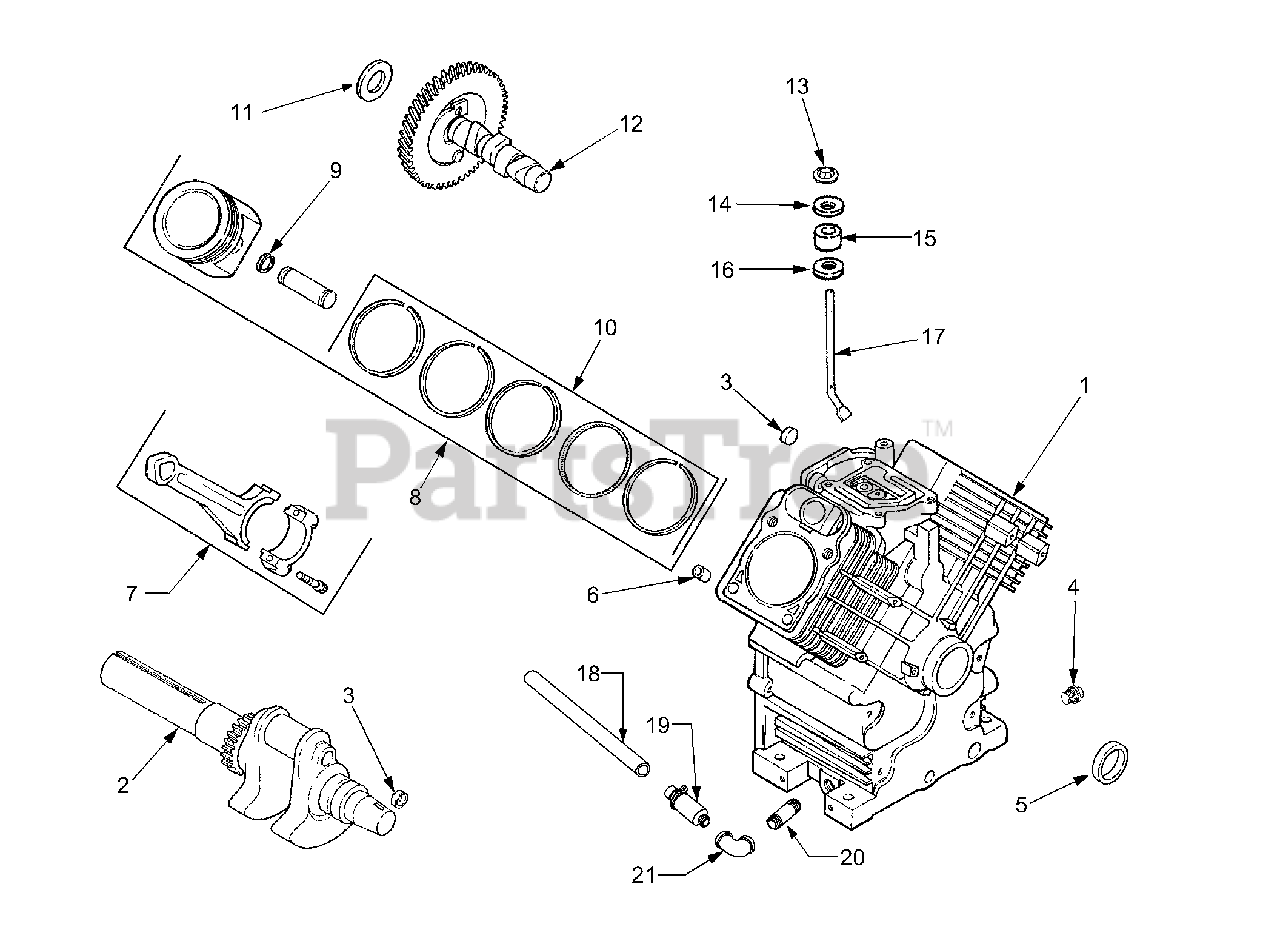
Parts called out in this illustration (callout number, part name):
1	Engine, Complete
2	Crankshaft
3	Plug, Cup
4	Plug, Hex Head, 3/8 NPTF
5	Seal, Oil
6	Pin, Dowel Locating
7	Rod, Connecting, Std
8	Piston w/Ring Set, Std
9	Retainer, Piston Pin
10	Ring Set, Std
11	Shim, Camshaft, .0320
12	Camshaft
13	Ring, Retainer
14	Washer, Nylon
15	Seal, Governor Cross Shaft
16	Washer, Plain
17	Shaft, Governor Cross
18	Hose, Oil Drain
19	Drain, Oil
20	Pipe, Straight
21	Elbow, 90°.
